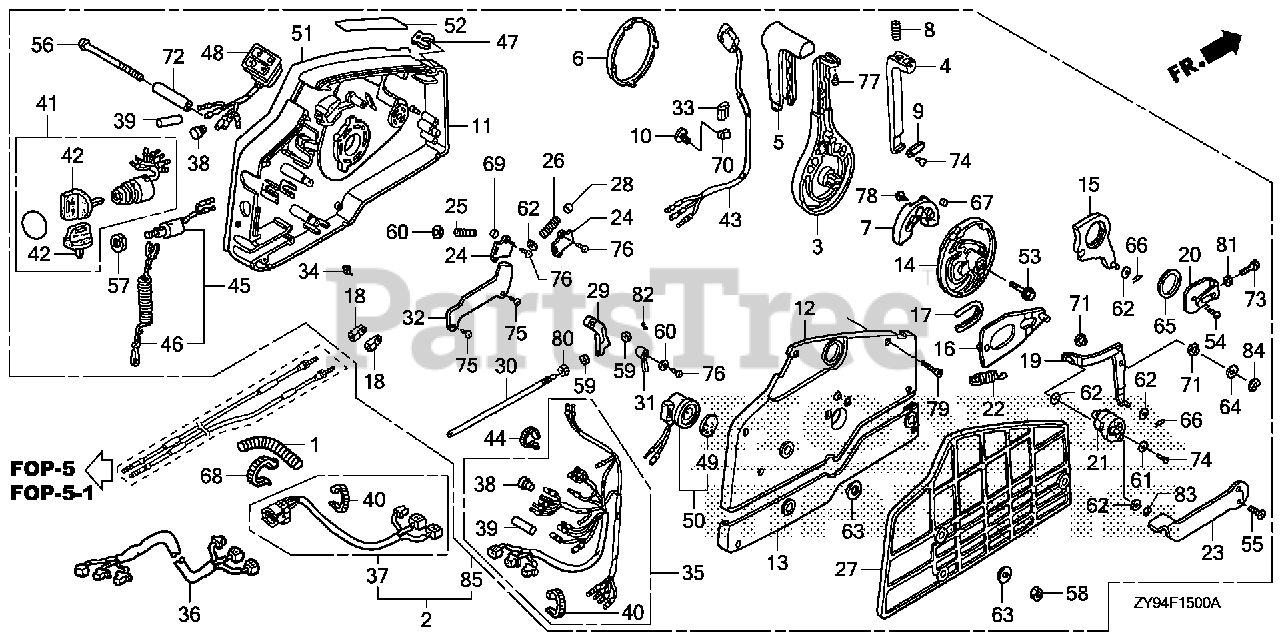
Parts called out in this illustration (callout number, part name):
1	TUBE, CORRUGATE (28MM)
2	BOX ASSY., REMOTE CONTROL (NHK MEC)
2	BOX ASSY., REMOTE CONTROL (P/T)(HI-LEX)
3	HANDLE, REMOTE CONTROL
4	LEVER, HANDLE LOCK
5	GRIP, REMOTE CONTROL HANDLE
6	CAP, HANDLE
7	BLOCK, NEUTRAL LOCK
8	SPRING, REMOTE CONTROL HANDLE
9	PLATE, LEVER SETTING
10	CLAMP, HARNESS
11	HOUSING, REMOTE CONTROL BOX (A)
12	HOUSING, REMOTE CONTROL BOX (B)
13	HOUSING, REMOTE CONTROL BOX (C)
14	WHEEL, CONTROL
15	ARM, SHIFT LINK
16	PLATE, SLIDING
17	COLLAR, SLIDING PLATE
18	PIVOT, SHIFT
19	ARM, LINK JOINT
20	BRACKET, LINK JOINT
21	WHEEL, ACCELERATOR
22	SPRING, ACCELERATOR WHEEL
23	LEVER, IDLE
24	PLATE, SPRING SETTING
25	SPRING, SHIFT CLICK
26	SPRING, CHOKE RETURN
27	SPACER, REMOTE CONTROL BOX
28	SPACER, CLICK SPRING
29	BLOCK, THROTTLE FRICTION
30	BOLT, FRICTION
31	SPACER, NEUTRAL SWITCH
32	CLAMP, POWER TILT CORD
33	PIPE, HARNESS GUIDE
34	SPACER, CABLE CLAMP
35	CABLE ASSY., REMOTE CONTROL (B) (FOR 2-LED)
35	CABLE ASSY., REMOTE CONTROL (B) (FOR 4-LED)
36	CABLE ASSY., REMOTE CONTROL EXTENSION (FOR 2-LED)
37	CABLE ASSY., SWITCH PANEL
37	CABLE ASSY., SWITCH PANEL (25FT) (NHK MEC)
37	CABLE ASSY., SWITCH PANEL (20FT) (FOR 4-LED)
37	CABLE ASSY., SWITCH PANEL (30FT) (FOR 4-LED)
38	PLUG, CONNECTOR (INNER)
39	PLUG, CONNECTOR (OUTER)
40	TIE, CABLE (2.4X92) (NATURAL)
41	SWITCH ASSY., COMBINATION
42	KEY ASSY., COMBINATION SWITCH (35100-ZV5-003 ONLY)
43	SWITCH ASSY., POWER TRIM-TILT
44	BAND (BLACK 3.5X140)
45	SWITCH ASSY., EMERGENCY STOP
46	WIRE, EMERGENCY
47	CLIP, EMERGENCY LOCK
48	LAMP ASSY., INDICATION (2-LED)
48	LAMP ASSY., INDICATION
49	PLATE, TURN SIGNAL BUZZER
50	BUZZER, WARNING
51	PLATE, REMOTE CONTROL (CAUTION PICT=SILVER) (FOR 2-LED)
51	PLATE, REMOTE CONTROL (CAUTION PICT=SILVER) (FOR 4-LED)
51	PLATE, REMOTE CONTROL (COUTION COLOR=RED & YELLOW)
52	MARK, FAST IDLE
53	BOLT, FLANGE (8X35)
54	SCREW, PAN (6X10)
55	SCREW, FLAT (5X12)
56	SCREW (6X95)
57	NUT, HEX. (16MM)
58	NUT, HEX. (6MM)
59	WASHER, PLAIN (4MM)
60	WASHER, PLAIN (5MM)
61	WASHER, PLAIN (5MM)
62	WASHER, PLAIN (6MM)
63	WASHER (6MM)
64	WASHER, PLAIN (8MM)
65	WASHER (28MM)
66	PIN, LOCK (6MM)
67	PIN (6X6)
68	BAND, SELF-LOCK
69	ROLLER, CLICK
70	CLIP, WIRE HARNESS (6.3MM)
71	COLLAR, LINK JOINT
72	COLLAR, DISTANCE (6X10X43.5)
73	BOLT, HEX. (5X16)
74	SCREW, PAN (5X10)
75	SCREW, TAPPING (5X8)
76	SCREW, TAPPING (5X10)
77	SCREW, TAPPING (5X12)
78	SCREW, TAPPING (6X16)
79	SCREW, TAPPING (5X25)
80	NUT, HEX. (6MM)
81	NUT, HEX. (5MM)
82	E-RING (3MM)
83	E-RING (4MM)
84	E-RING (7MM)
85	BOX ASSY., REMOTE CONTROL (NHK MEC)
85	BOX ASSY., REMOTE CONTROL (TROLLING CONTROL)(NHK MEC)
